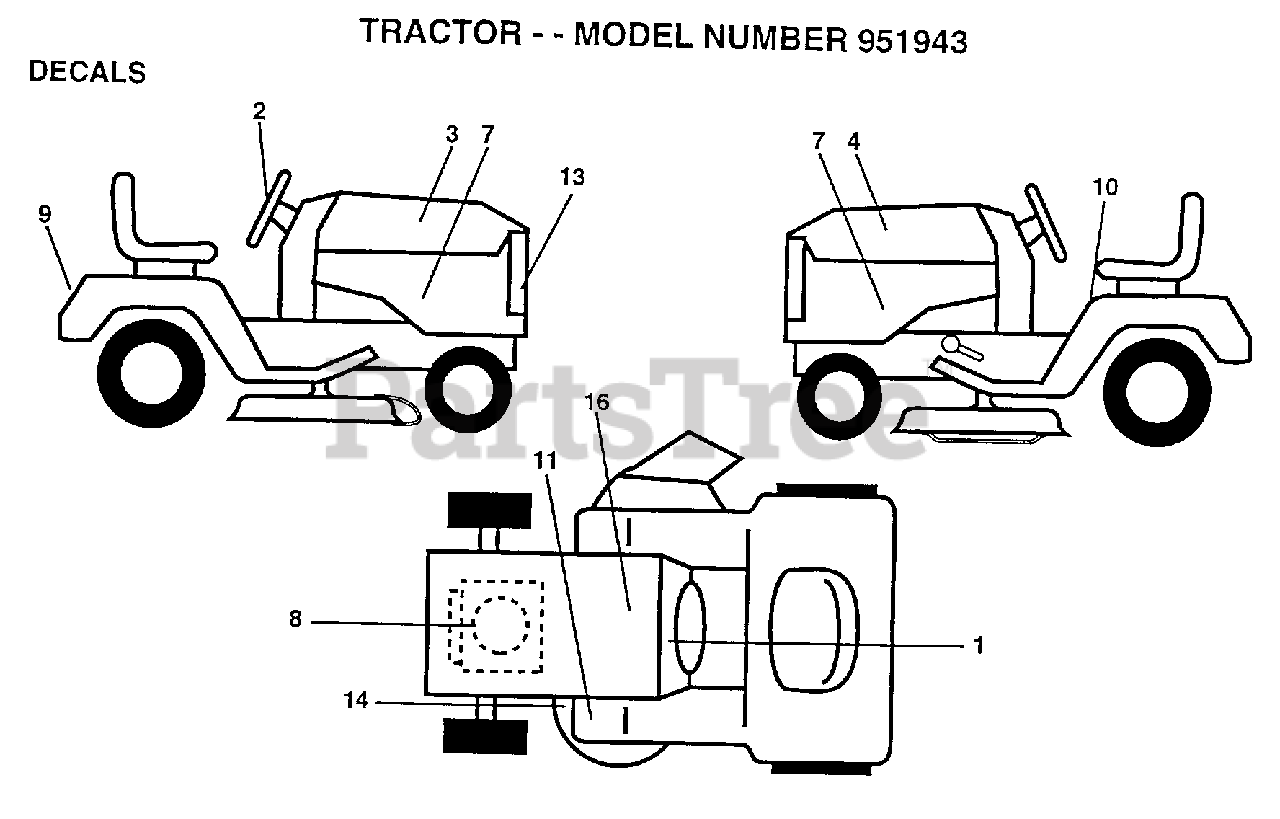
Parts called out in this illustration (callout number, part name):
1	DECAL.DASH.INST.
2	DECAL.INS.WHL.STG
4	DECAL HOOD LH
7	DECAL.PANEL.SIDE
8	DECAL KOHLER 20 OHP DMD
10	DECAL
13	DECAL.GRILL.YARDP
14	"DECAL.V.BELT.44"""
16	DECAL.BTRY.DANGER
